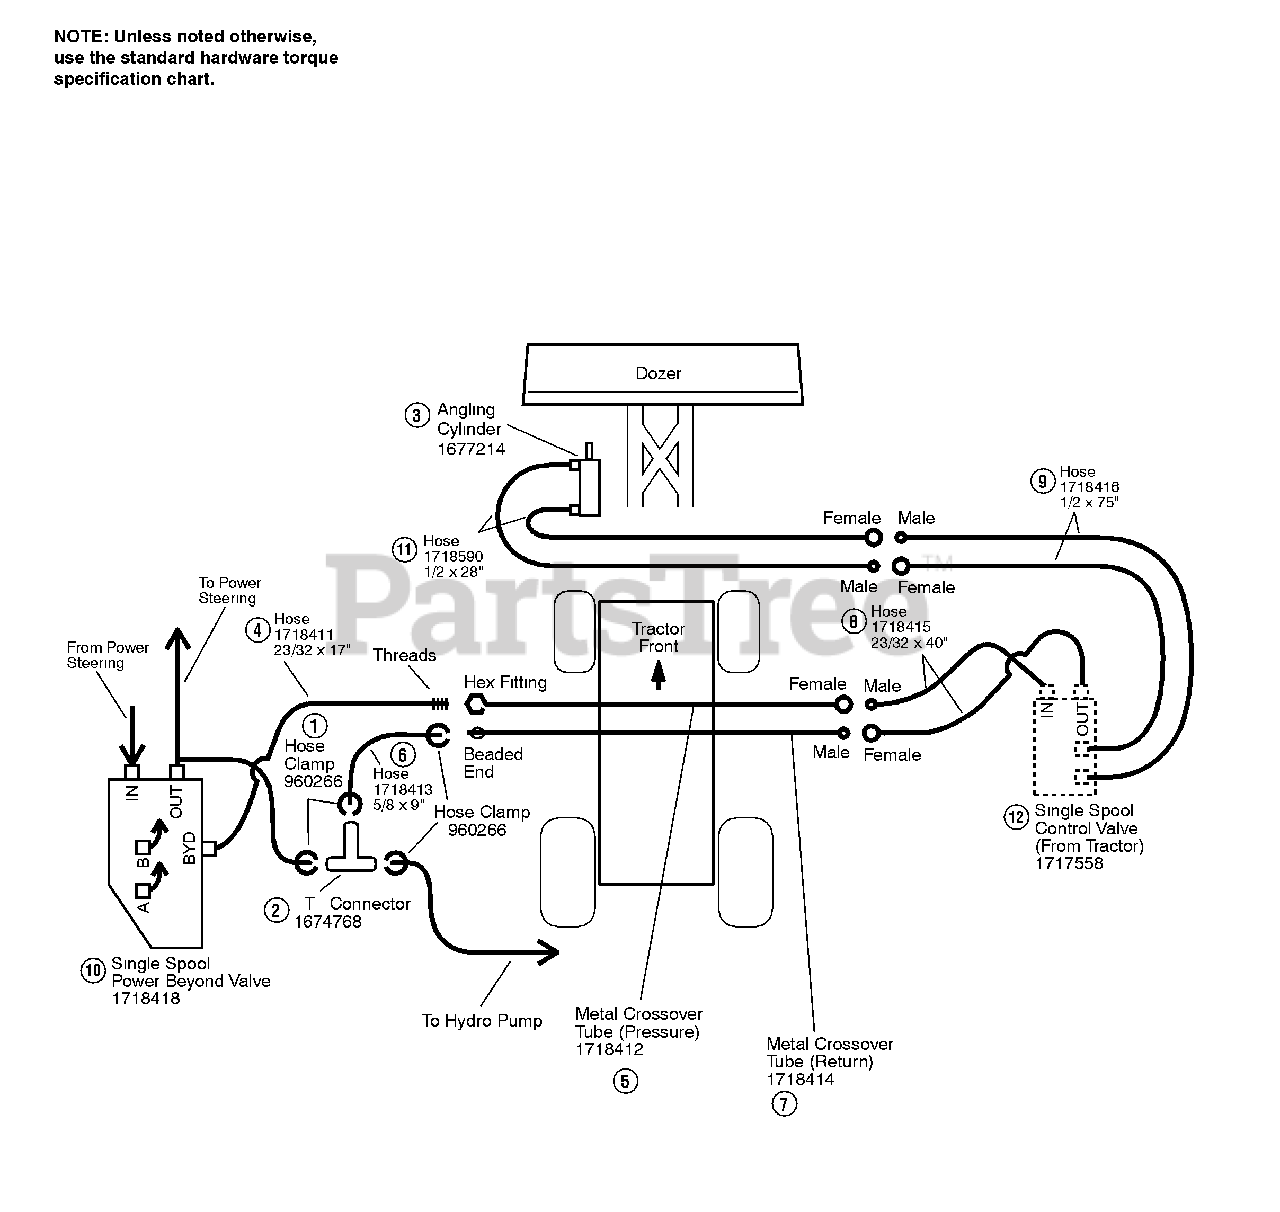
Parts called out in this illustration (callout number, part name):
1	CLAMP, Hose, Worm
2	FITTING, Hose, Tee
3	CYLINDER, Angling
4	HOSE ASSEMBLY, 23/32" x 17"
5	TUBE, Metal Cross-Over (Pressure)
6	HOSE, Hydraulic 3/8" ID x 9"
7	TUBE, Metal Cross-Over (Return)
8	HOSE, Hydraulic, 23/32" x 40"
9	HOSE, Hydraulic, 1/2" x 75"
10	CONTROL VALVE, Single Spool, Power Beyond
11	HOSE, Hydraulic, 1/2" x 28"
12	CONTROL VALVE, Single Spool (From Tractor)
